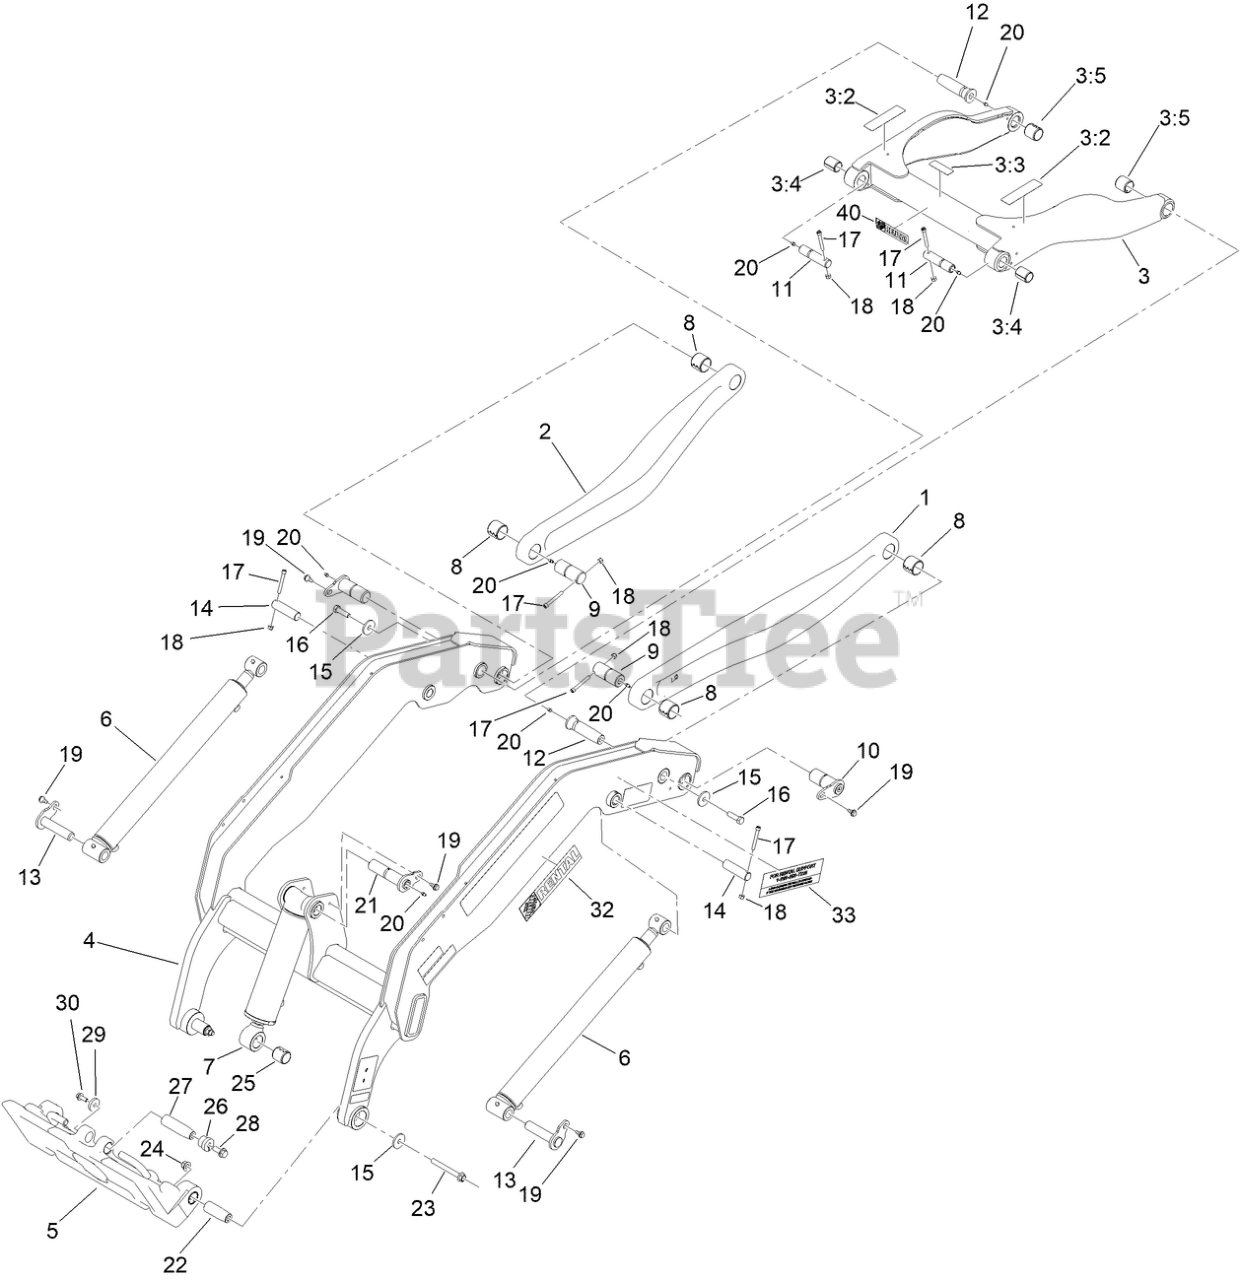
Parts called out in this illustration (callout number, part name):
1	LINK-LOWER, LH [BLK-TXT]
2	LINK-LOWER, RH [BLK-TXT]
3	UPPER LINK ASM-LOADER
3:2	DECAL-WARNING, CRUSHING
3:3	DECAL-WARNING, PINCH POINT
3:4	BUSHING-SPRING
3:5	BUSHING-SPRING
4	LOADER ARM ASM-WT
5	ATTACHMENT PLATE ASM
6	CYLINDER HYD (2.25X20.16 DOUBLE ACTION)
7	CYL-HYD
8	BUSHING-SPRING
9	PIN-ARM
10	PIN-PIVOT
11	PIN-LINK
12	PIN-TAPER
13	PIN-FLAG
14	PIN-PIVOT
15	WASHER-THRUST
16	SCREW-HH
17	SCREW-HSH
18	NUT-LOCK, NI
19	BOLT-SHOULDER
20	FITTING-GREASE
21	FLAG PIN ASM
22	PIN-LINK,TAPER
23	SCREW-HHF
24	NUT-LOCK
25	BUSHING-SPRING
26	INSERT-TAPERED
27	PIN-TAPERED
28	SCREW-HHF
29	WASHER-CLUTCH
30	SCREW-HHF
32	DECAL - HDHLW3X10
33	DECAL-CPER0002
40	DECAL - HDHLW1X5
